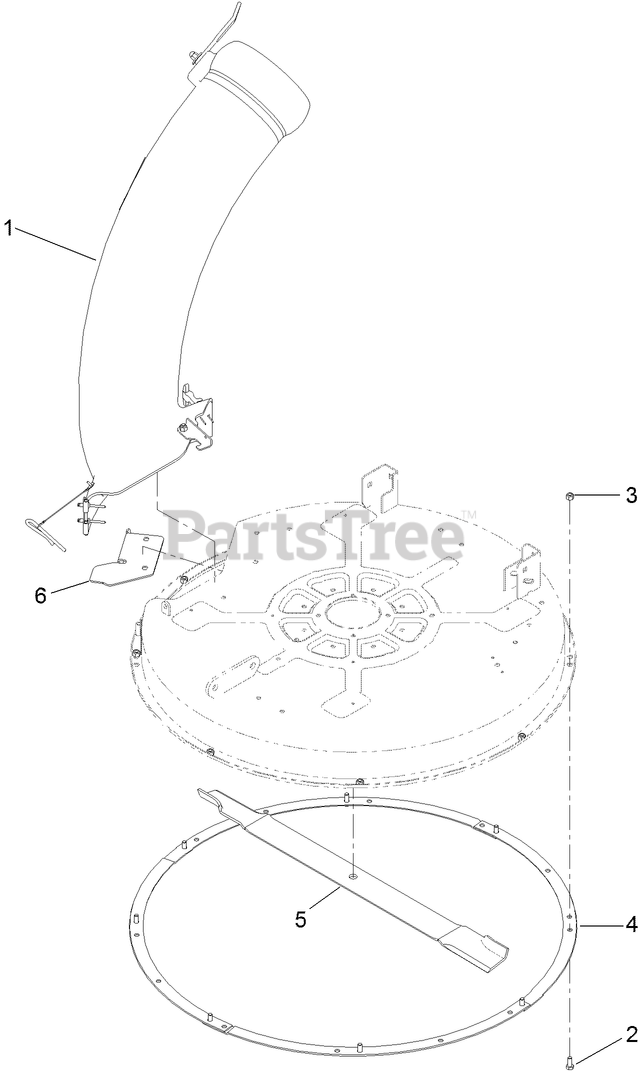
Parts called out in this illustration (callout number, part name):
1	32 INCH CHUTE ASM
2	SCREW-HH
3	NUT-LOCK, NI
4	RING-DECK
6	BRACKET-CUTOFF
